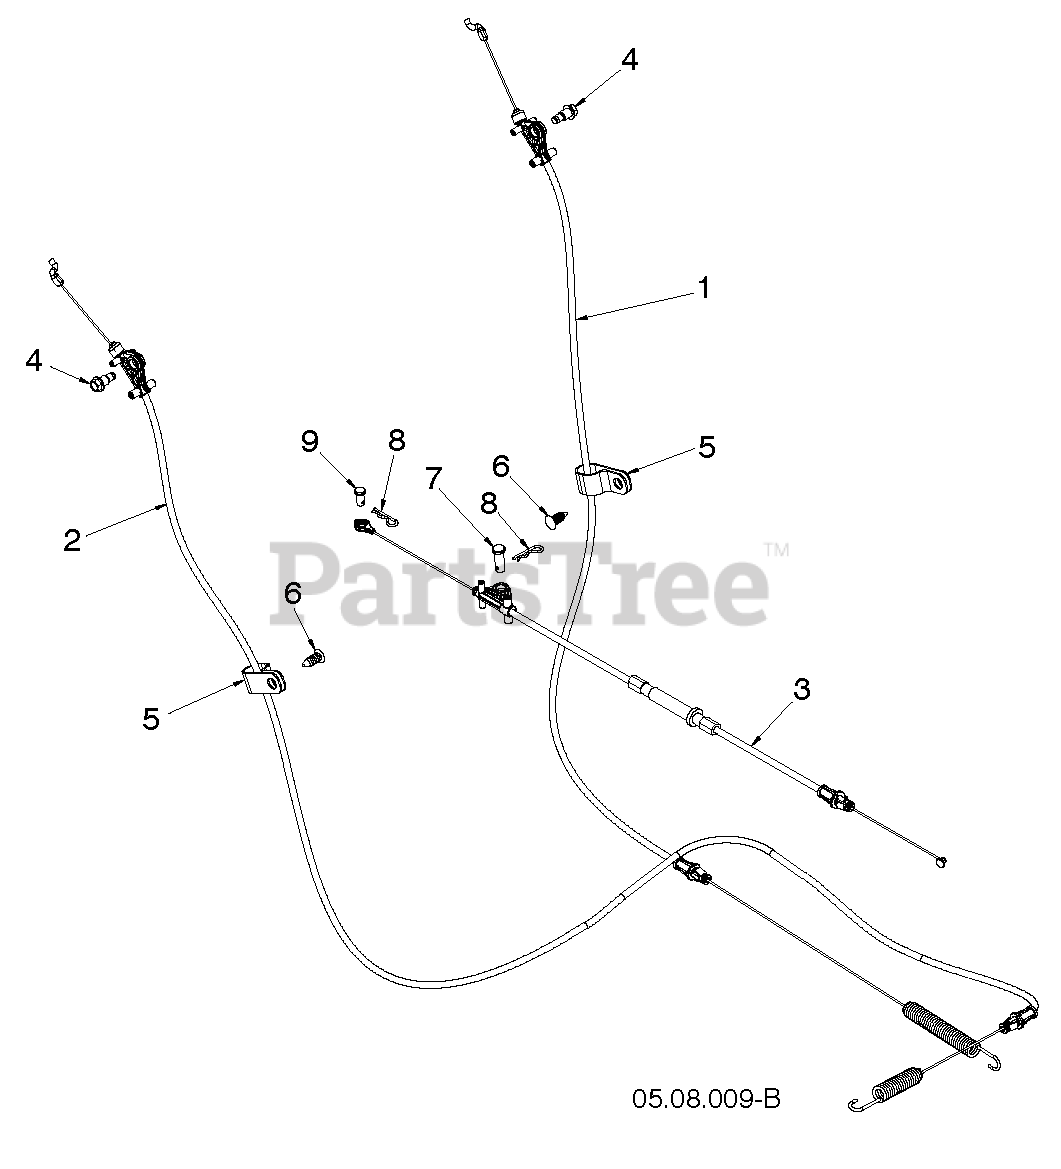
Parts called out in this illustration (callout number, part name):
1	Drive Control Cable, DSST OPP
2	Auger Control Cable, DSST High-Crank
3	Speed Selector Cable
4	Shoulder Bolt, 1/4-20 Trilob
5	CLIP.CABLE.BLK
6	FASTENER.PUSH.O.250X0.783
7	Clevis Pin, 5/16 X .875
8	Hair Pin, .059 X 1.125
9	Clevis Pin, .25 X .31
